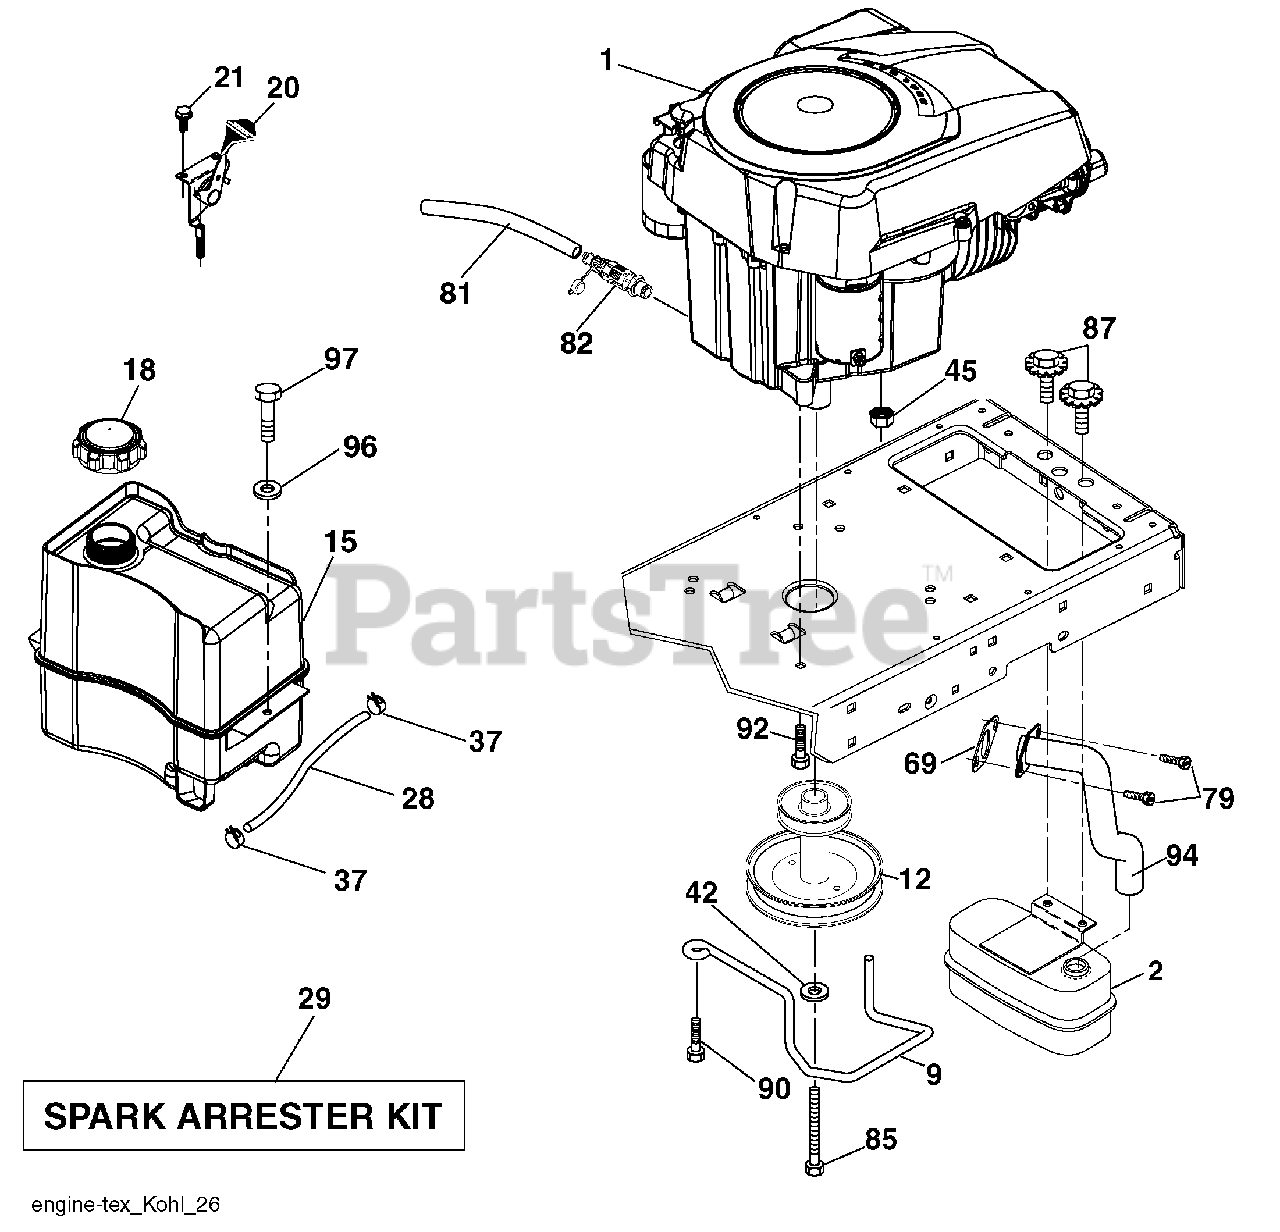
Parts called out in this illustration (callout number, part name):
9	Keeper Belt Engine
12	Pulley Engine
15	Tank Fuel
18	Cap Asm
20	Control Throttle/Choke
21	Screw #10 x 0.750 BOS Thread
28	Fuel Line
29	Spark Arrester Kit
37	Clamp Hose
42	Washer Lock 7/16
45	Nut Keps Hex 1/4-20 unc
79	Screw Socket Head
81	Tube Drain Oil Easy
82	Valve Drain Oil
85	Bolt Hex 7/16-20 x 4 x Gr. 5-1.5 Thr
87	Bolt 5/16-18 unc x 3/4 w/Sems
90	Screw 3/8-16 x 1
92	Screw 3/8-16 x 1
94	Tube Exhaust
96	Washer 9/32 x 7/8 x 16 Ga.
97	Screw Hexwsh Thdrol 1/4-20 x 3/4
